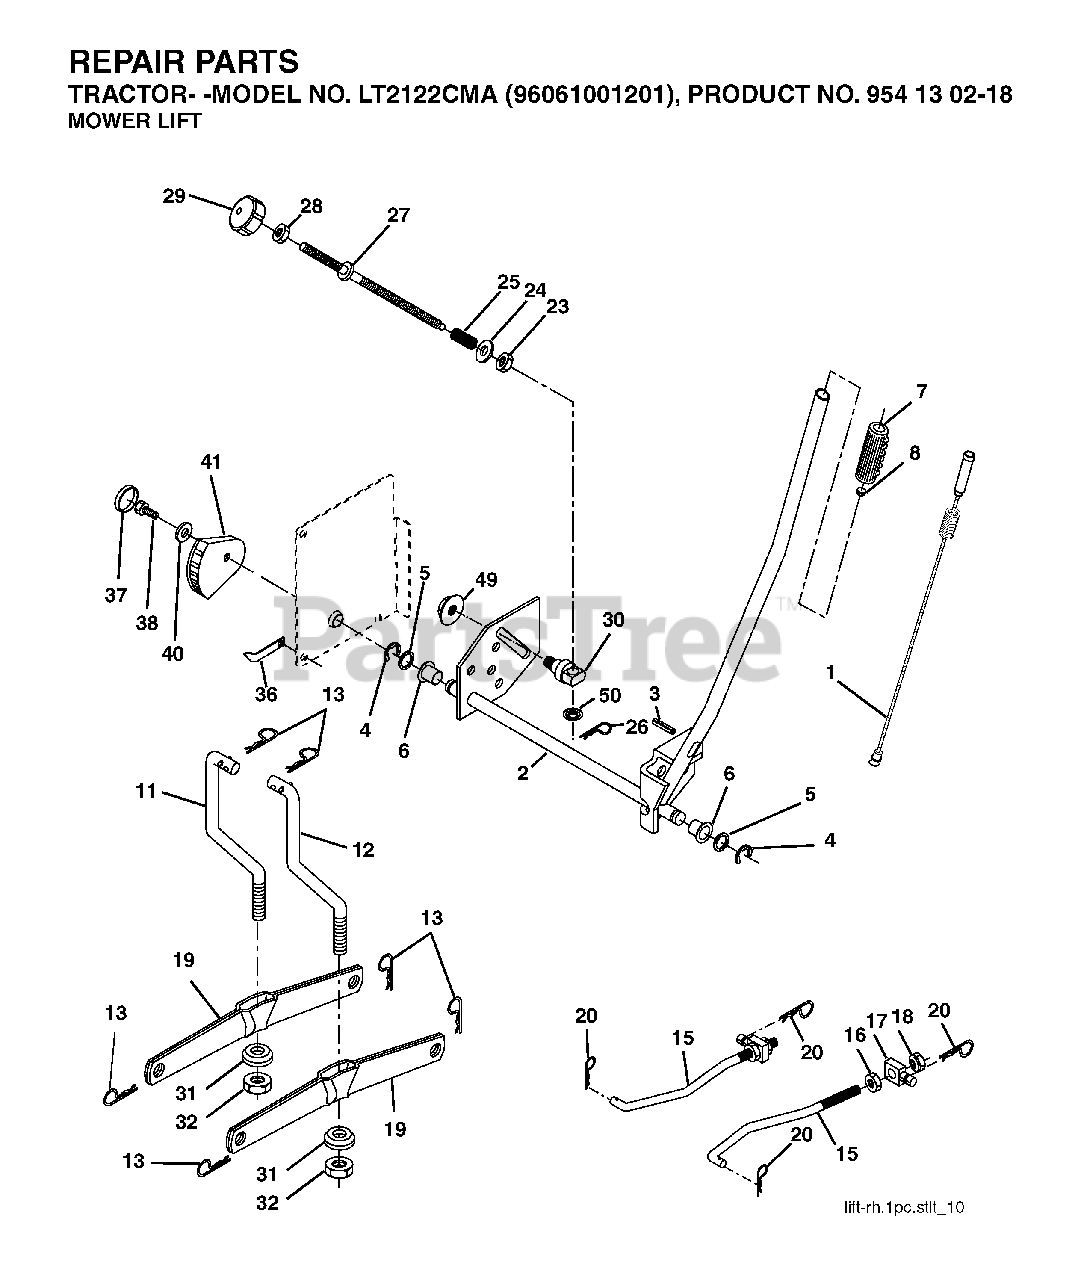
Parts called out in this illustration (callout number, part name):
1	WIRE, INNER
4	RETAINING RING LT
6	BEARING.NYLON
7	GRIP HANDLE
8	PLUNGER BUT KIT
11	LINK
12	LINK
13	RETAINER-SPRNG RB
15	LINK.SUSPENSION.FRONT
16	NUT
18	NUT
19	ARM.REAR.SUSPENSION
20	SPRING RETAINER
26	RETAINER CLIP
28	NUT
29	KNOB INF 3/8-16
31	BEARING.PIVOT.LIFT
32	NUT CROWNLOCK 3/8-24
36	POINTER, HEIGHT INDICATOR
37	PLUG,HOLE
38	SCREW 5/16-18X1
41	HEIGHT INDICATOR
49	NUT
50	NUT PUSH M
